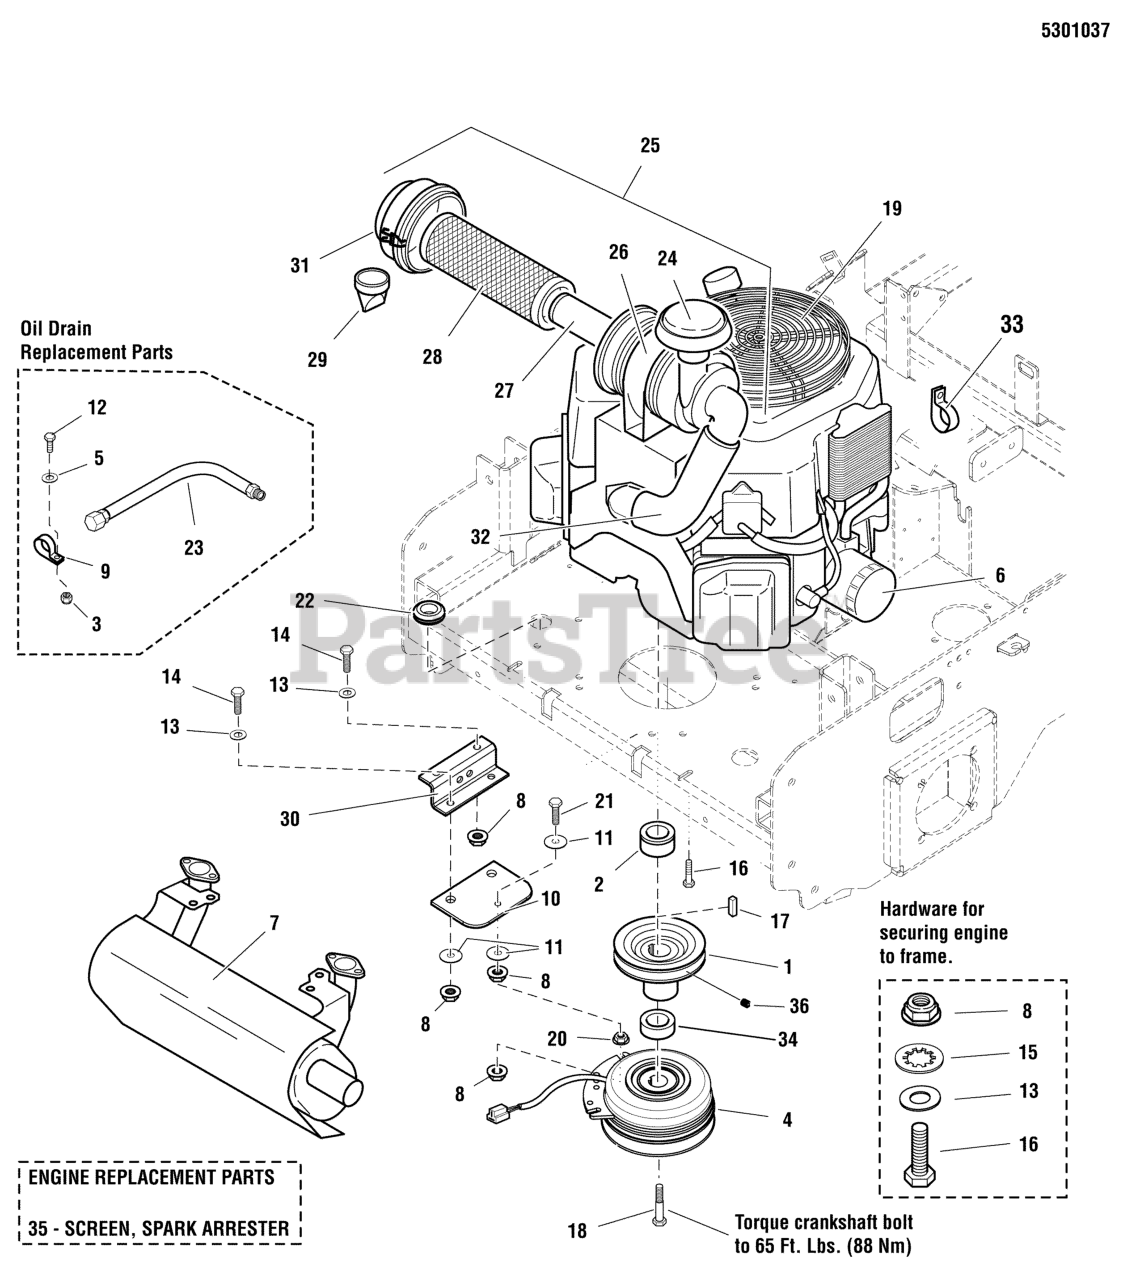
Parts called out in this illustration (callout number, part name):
1	PULLEY, 5.15 OD X 1-1/8 BORE B-SECT
2	SPACER, 1.13 X 1.75 X 1.03 YZ
3	NUT, 1/4-20 HEX NYLOCK FLANGE
4	* CLUTCH, 5218-134, WARNER
5	WASHER, 1/4 SAE
6	OIL FILTER, KOHLER (SV)
7	MUFFLER, KOHLER 21 HP - 27 HP
8	NUT, 5/16-18 HEX NYLOCK FLANGE
9	CLAMP, VINYL INSULATED
10	CLUTCH ANCHOR PAD
11	WASHER, .34 X 1.25 X 10 GA
12	BOLT, 1/4-20 X 3/4 GD5 YZ
13	WASHER, 5/16" SAE
14	BOLT, 5/16-18 X 1 GD5 YZ
15	WASHER, 5/16" INT. TOOTH LOCK
16	BOLT, 5/16-18 X 1-3/4 GD5 YZ
17	KEY, 1/4 SQ X 1
18	BOLT, CRANKSHAFT, 7/16" X 2-1/4"
19	* ENGINE, 27HP KOHLER
20	NUT, 5/16-18 HEX SERRATED FLANGE (LARGE)
21	BOLT, 5/16-18 X 2-1/4 TFL, GD5 YZ
22	GROMMET, 7/8
23	HOSE, OIL DRAIN
24	RAIN COVER (SV)
25	KIT, AIR FILTER ASSEMBLY (SV)
26	MOUNT, BRACKET, HOUSING (SV)
27	AIR FILTER, SECONDARY (SV)
28	AIR FILTER, PRIMARY (SV)
29	DUST VALVE (SV)
30	ANCHOR, CLUTCH - BLK
31	END CAP (SV)
32	AIR INLET TUBE (SV)
33	CLAMP, HOSE, 1.000 DIA
34	SPACER, 1.13 X 1.75 X .75
36	SET SCREW, 5/16-18 X 3/8, KNURL, W/PATCH
